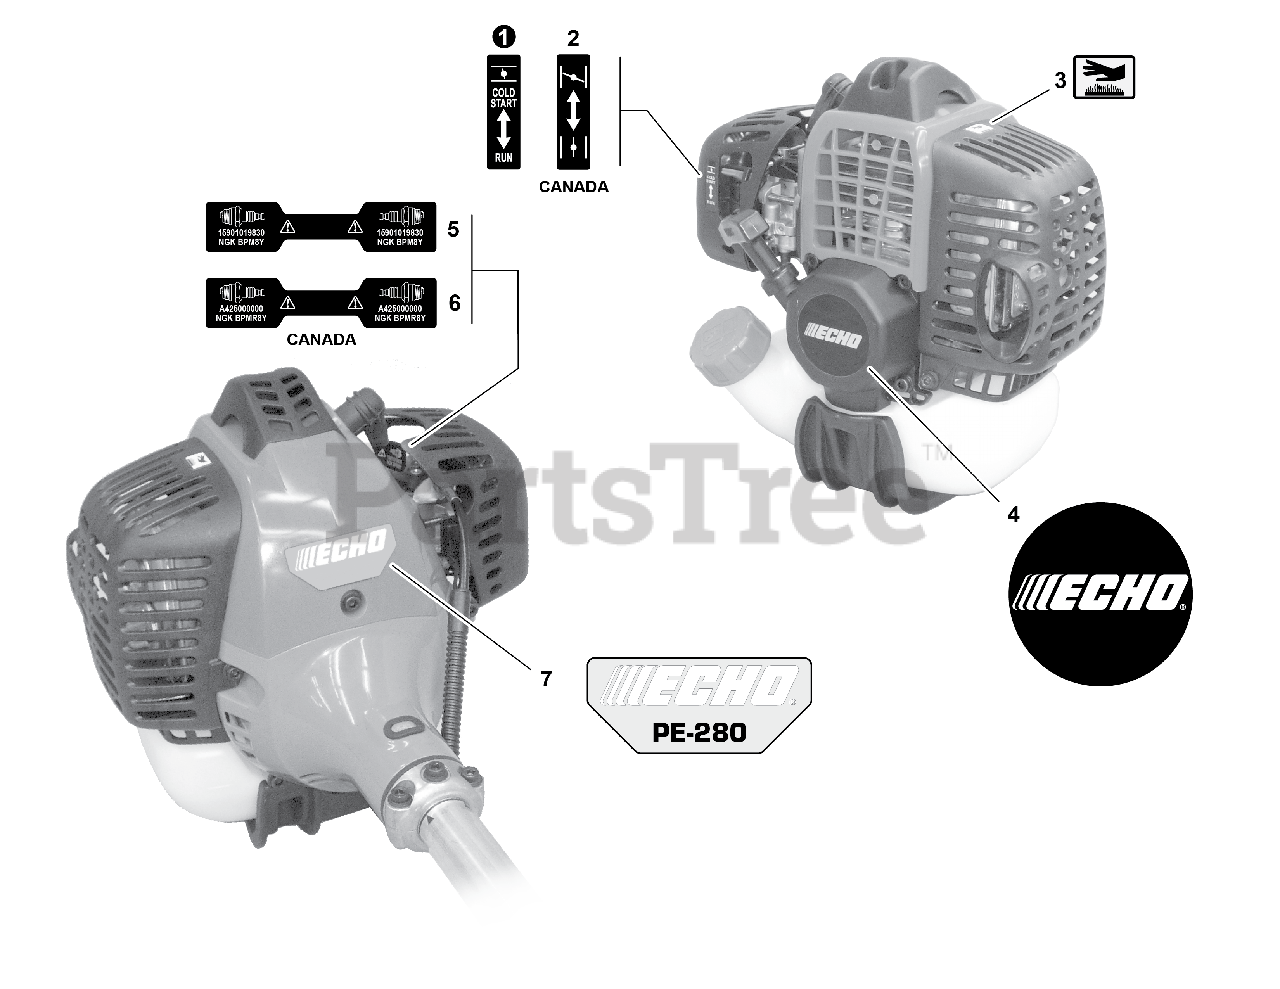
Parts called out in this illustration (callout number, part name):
1	LABEL - CHOKE
2	LABEL - CHOKE
3	LABEL - CAUTION -- HOT
4	LABEL - ECHO
5	LABEL - SPARK PLUG -- BPM8Y
6	LABEL - SPARK PLUG -- BPMR8Y
7	LABEL - MODEL -- PE-280
